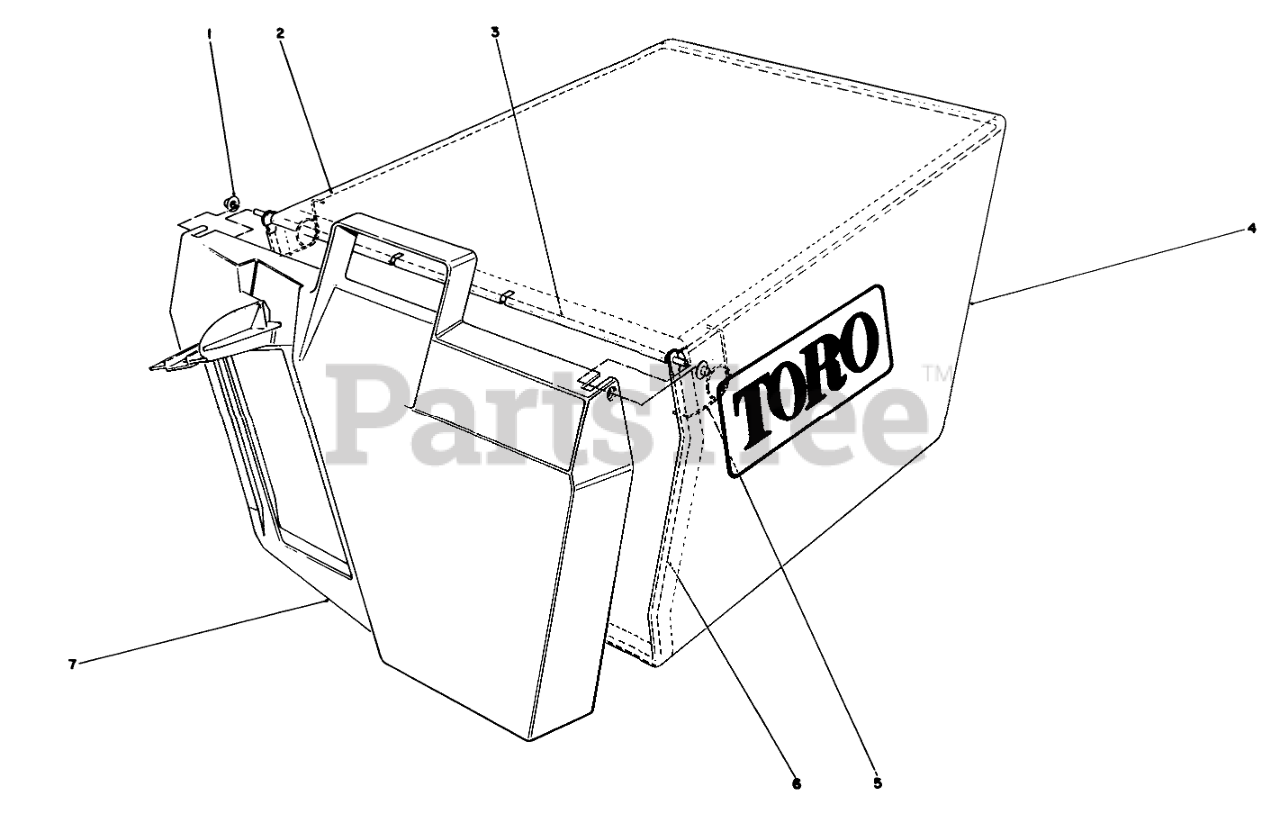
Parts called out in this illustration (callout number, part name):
1	NUT-PUSH
2	FRAME-BAG, UPPER
3	HINGE-DOOR, BAG
4	BAG-GRASS
5	SPRING
6	FRAME-BAG
7	DOOR-BAG
